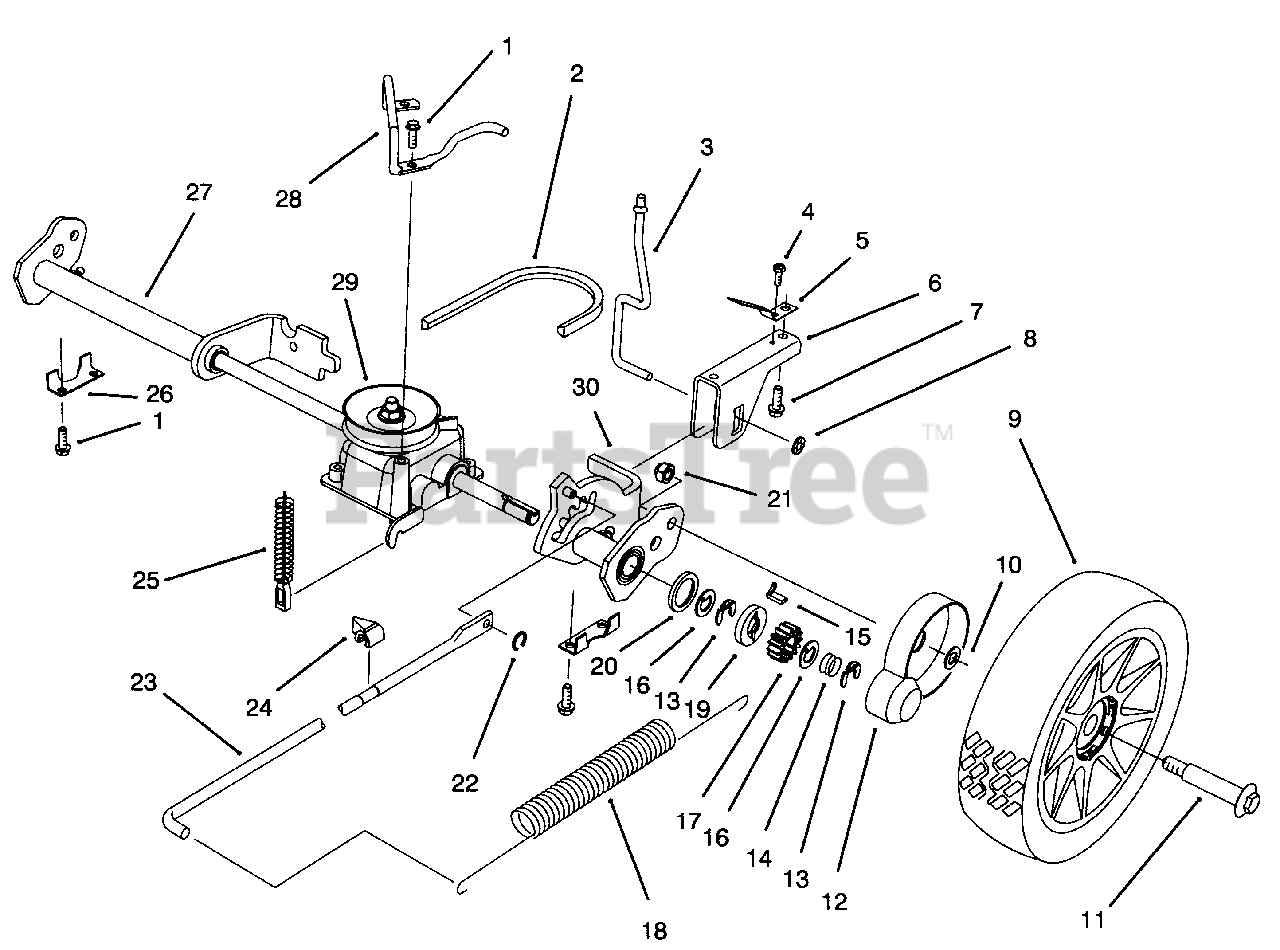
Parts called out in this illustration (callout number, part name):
1	Screw-Tapping
2	V-Belt-Gear Case
3	Rod-Trigger
4	Screw-Tapping
5	Spring-Trigger Retainer
6	Saddle-H.O.C.
9	Wheel & Tire Assembly
10	Spacer-Wheel
11	Bolt-Shoulder
12	Cover-Wheel
13	Ring-Retaining
14	Spring-Compression
15	Key-Rocking L.H.
16	Washer-Thrust Keyed
17	Gear-Pinion
18	Spring-Counterbalance
20	Ring-Friction
21	Nut-Lock
22	Ring-Grip
23	Rod-Link
24	Indicator-H.O.C.
25	Spring-Compression
26	Plate-Securing Rear
27	Arm-R.H. Pivot
28	Retainer-Belt
29	Case-Gear
30	Arm-L.H. Pivot
